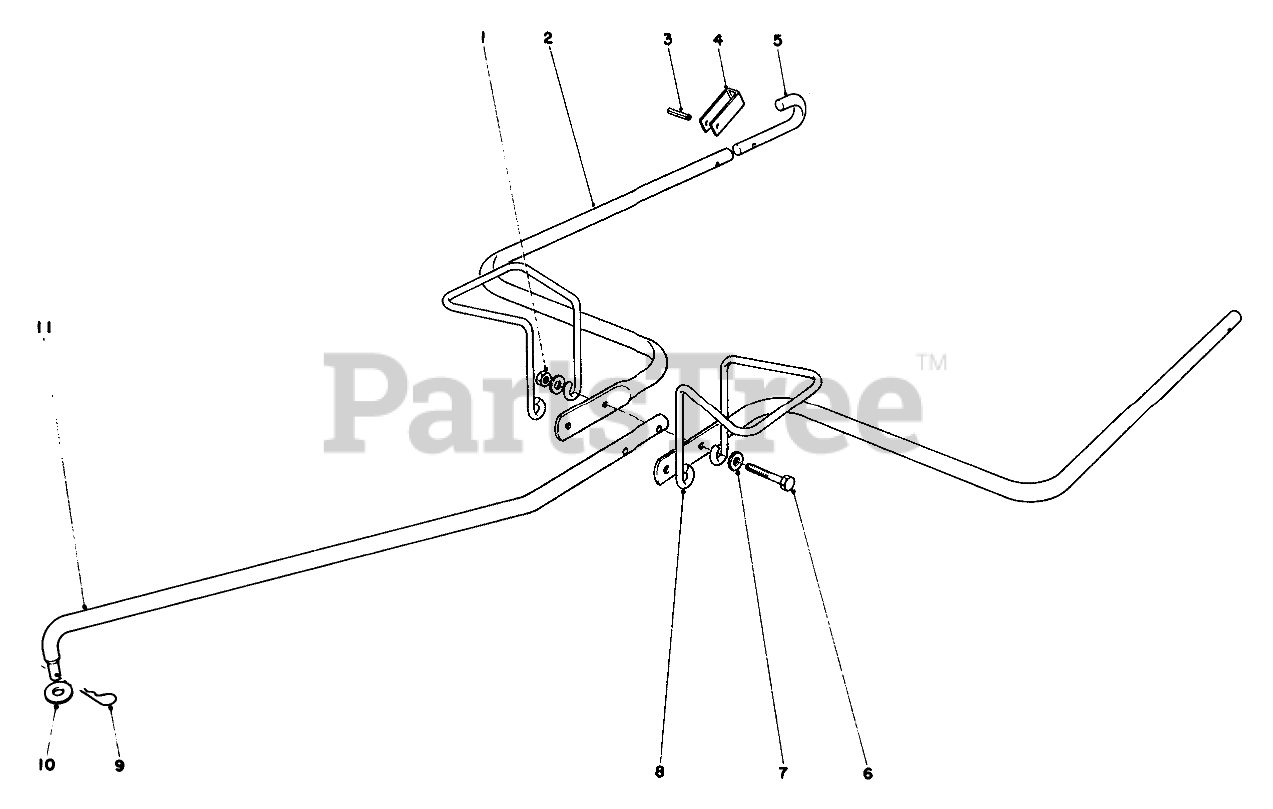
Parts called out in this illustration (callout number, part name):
1	NUT-LOCK, CONE
2	HITCH ARM
3	PIN-ROLL, SLOT
4	HITCH LOCK
5	HOOK HITCH ARM
6	SCREW-HH
7	WASHER-FLAT
8	Support Bag
9	PIN-COTTER
10	PUSH NUT
11	POLE HITCH
